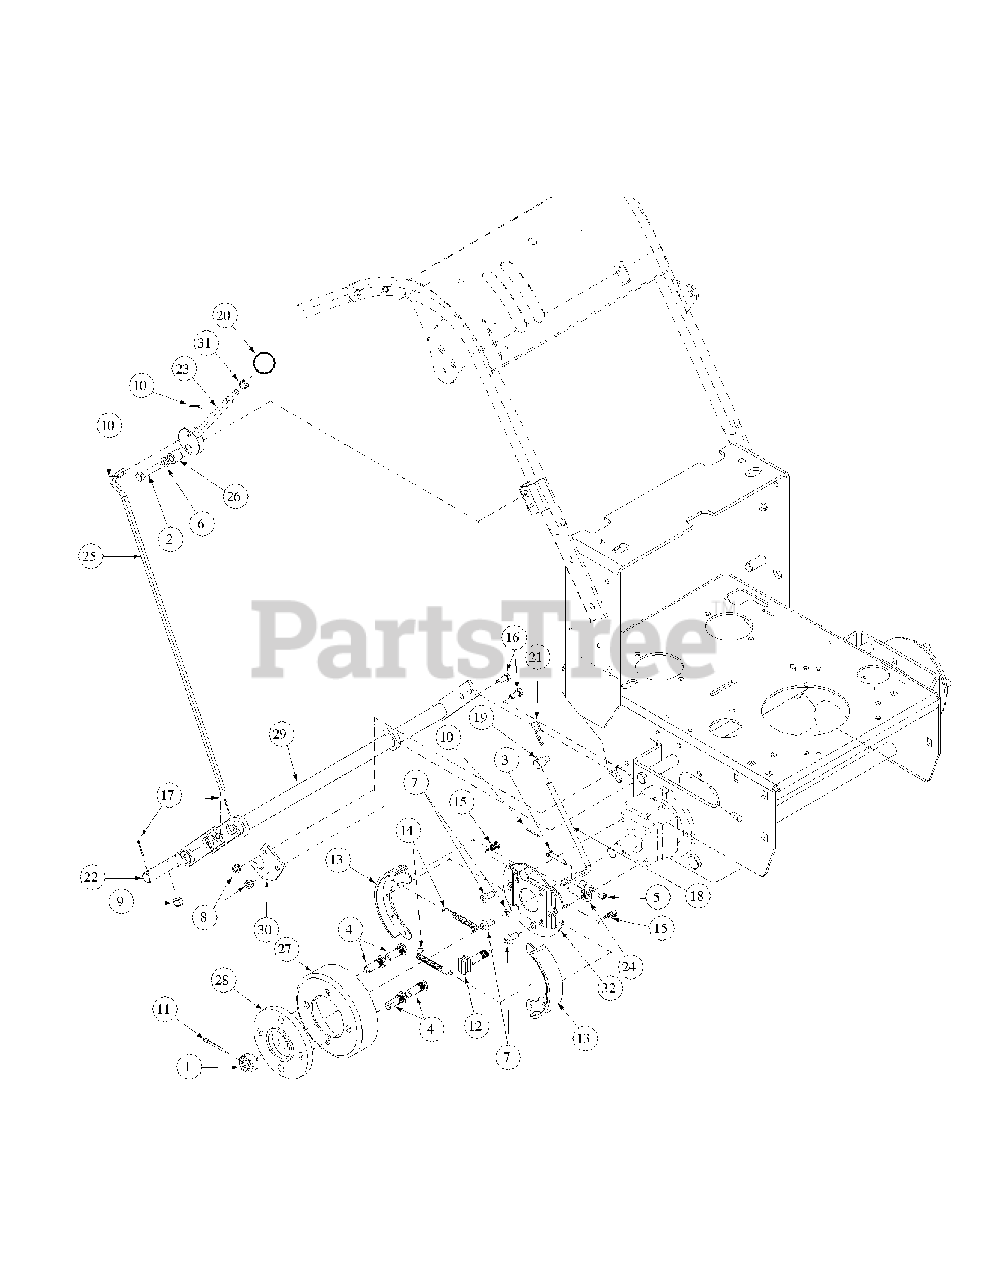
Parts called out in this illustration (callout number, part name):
1	Nut, Castle, 3/4-16
2	Capscrew, 3/8-16 x 1" Grade 5 Zinc
3	Cap Screw, 1/4-20 x 1.50, Grade 5
4	Bolt, Wheel, 1/2-20 x 1-3/8
5	Lock Nut, Nylon Insert, 1/4-20 Grade A
6	Lock Washer, 3/8 Zinc
7	Capscrew, Socket Button Hd., 3/8-16 x 3/4 Zinc
8	Nut, 5/16-18, Nylock
9	Nut, Nylon Insert, 3/8-16 Grade A
10	Cotter Pin, 3/32 x 3/4, Zinc
11	Cotter Pin, 5/32 x 1-1/2 Zinc
12	Brake Cam, Actuating
13	Brake Shoe w/Lining, 6 x 1-1/4
14	Brake Spring, Tension
15	Brake Spring, Anti-Vibration
16	Cap Screw, 5/16-18 x 3/4, Grade 5
17	Cotter Pin, 3/32 x 1, Zinc
18	Brake Rod
19	Swivel Joint
20	Knob, Red, Shift w/Insert
21	Hair Pin, 3/8"-1/2"
22	Joint, Brake Pull
23	Lever Assembly, Brake
24	Brake Clamp, Control Assembly, Hydro
25	Rod, Long Brake, Hydro WB
26	Pivot Spacer, Hydro WB
27	Brake Drum
28	Hub, Wheel Motor
29	Brake Shaft Assembly WT
30	Pivot Mount, Brake
31	Nut, 3/8-16, Jam, Grade 2
32	Brake Backing Plate
